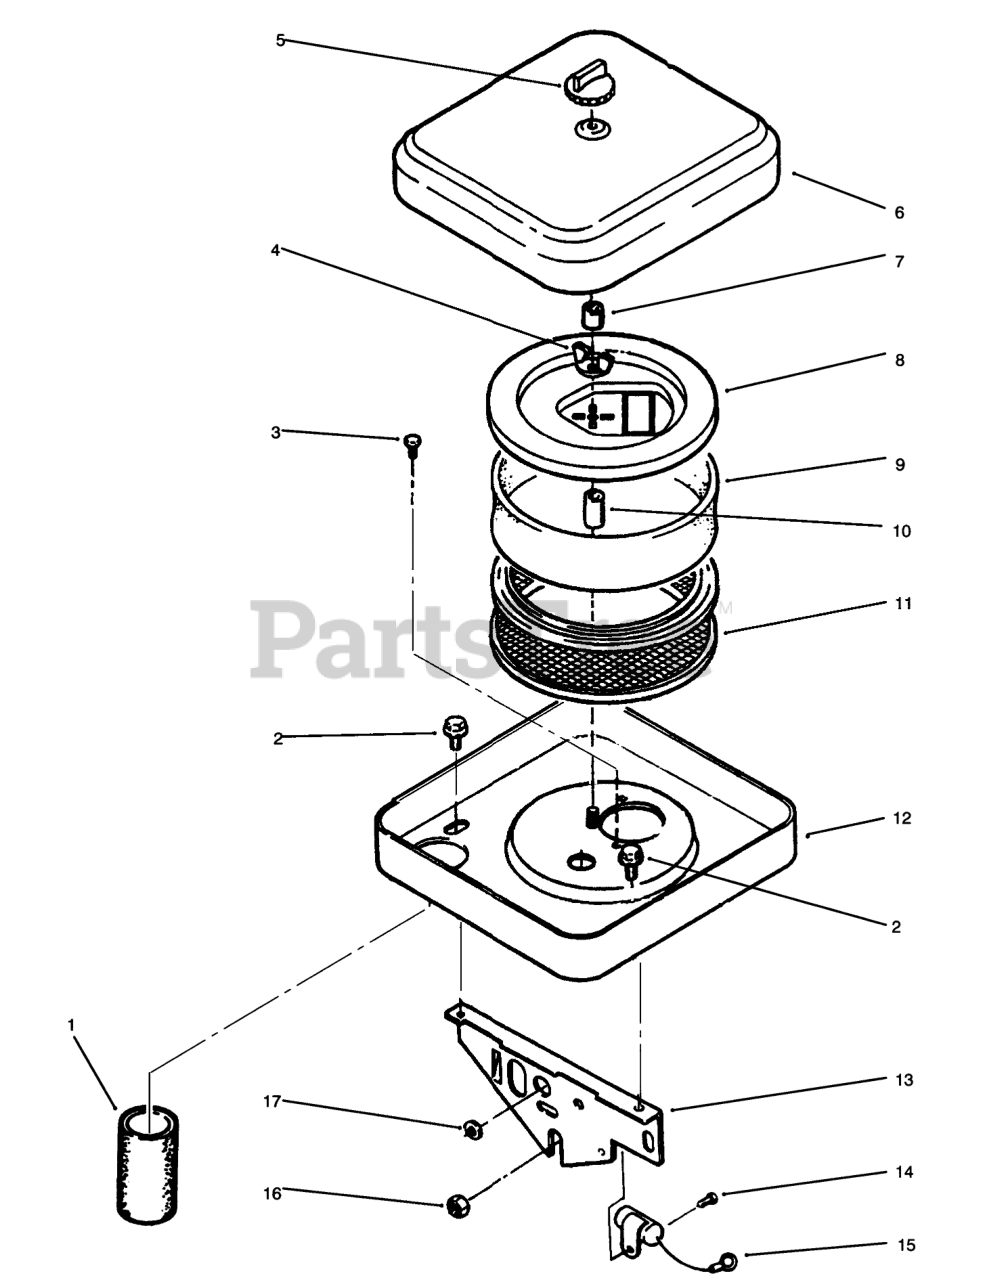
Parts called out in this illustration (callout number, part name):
1	AIR INTAKE TUBE
2	SCREW-TAPPING
3	MACHINE SCREW
4	1/4-20 WING NUT
6	CHROME-AIR CLEANER
7	SPACER-RUBBER
8	ELEMENT COVER KIT
9	AIR CLEANER ELEMENT
10	SPACER-1" LG
11	ELEMENT-AIR CLEANER
12	AIR-CLEANER HOUSING
13	SUPPORT-AIR CLEANER
14	SCREW #10-32 X 5/8
15	CONDENSER
16	WASHER-LOCK
17	GROMMET
